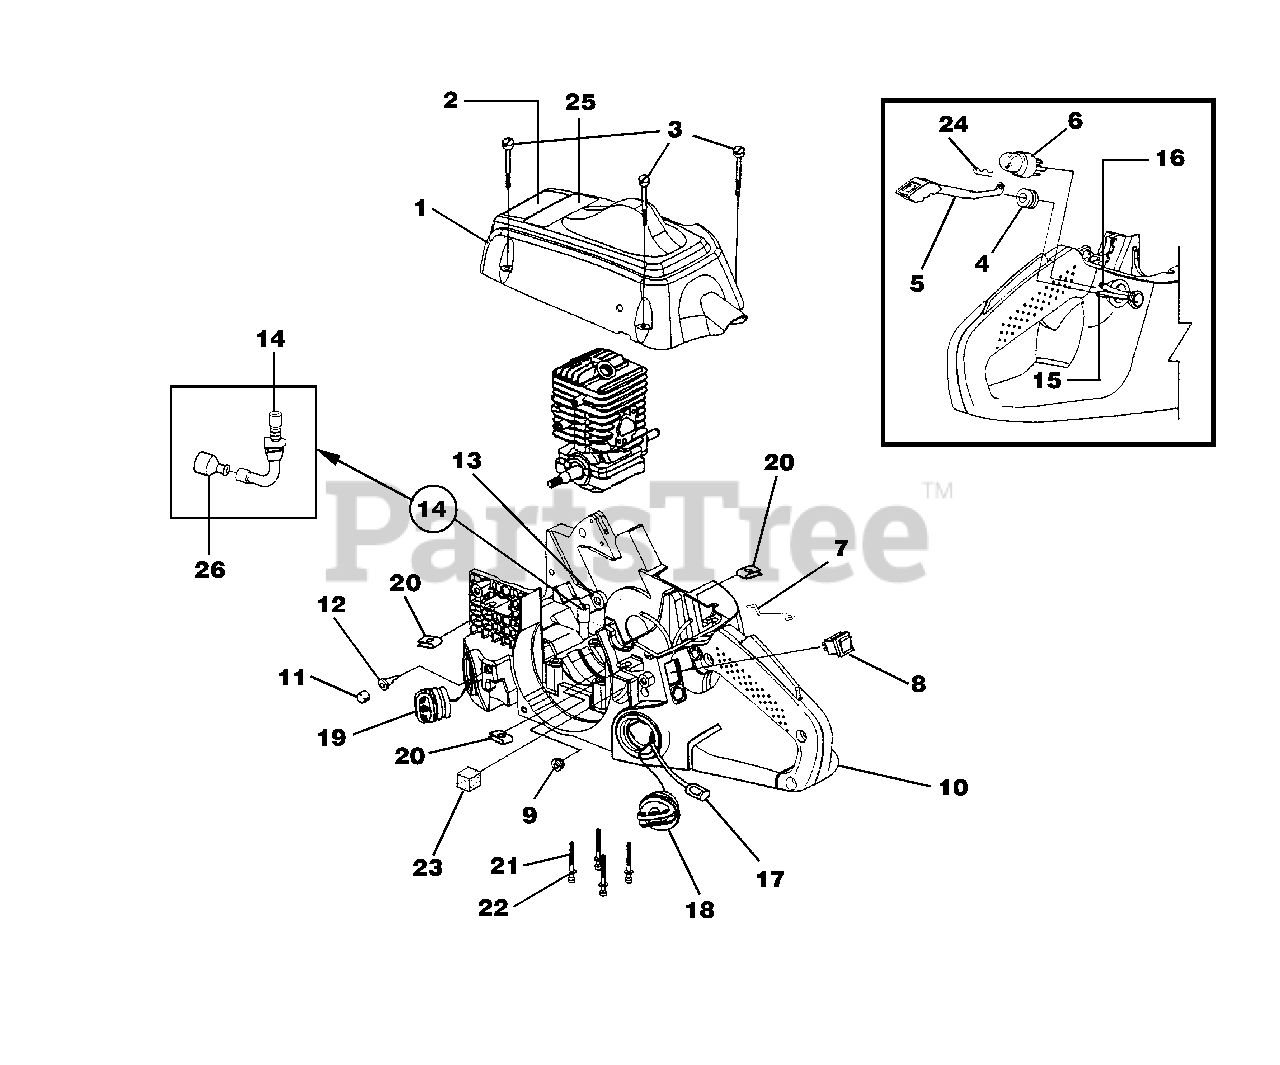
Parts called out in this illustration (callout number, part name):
1	Cylinder Cover Kit
2	Safety Decal
3	Screw-Slotted Pan Hd.
4	Grommet
5	Rod, Choke
6	Bulb, Air Purge
7	Throttle Wire
8	Switch, Rocker
9	Grommet-Split
10	Engine Housing
11	Element, Filter (Bronze)
12	Duck Bill Valve
13	Oil Outlet Grommet
14	Oil Intake Tube
15	Rubber Tubing (5 1/2")
16	Rubber Tubing (8 1/2")
17	Fuel Filter
18	Fuel Cap w/ Retainer
19	Oil Cap w/ Retainer
20	Speed Nut ("U-Type")
21	Screw, Cap-Socket Hd. (10-24 x 2")
22	Washer
23	Pre Filter
24	Spring Clip (Choke Rod)
25	Kickback-Decal
26	Oil Filter
